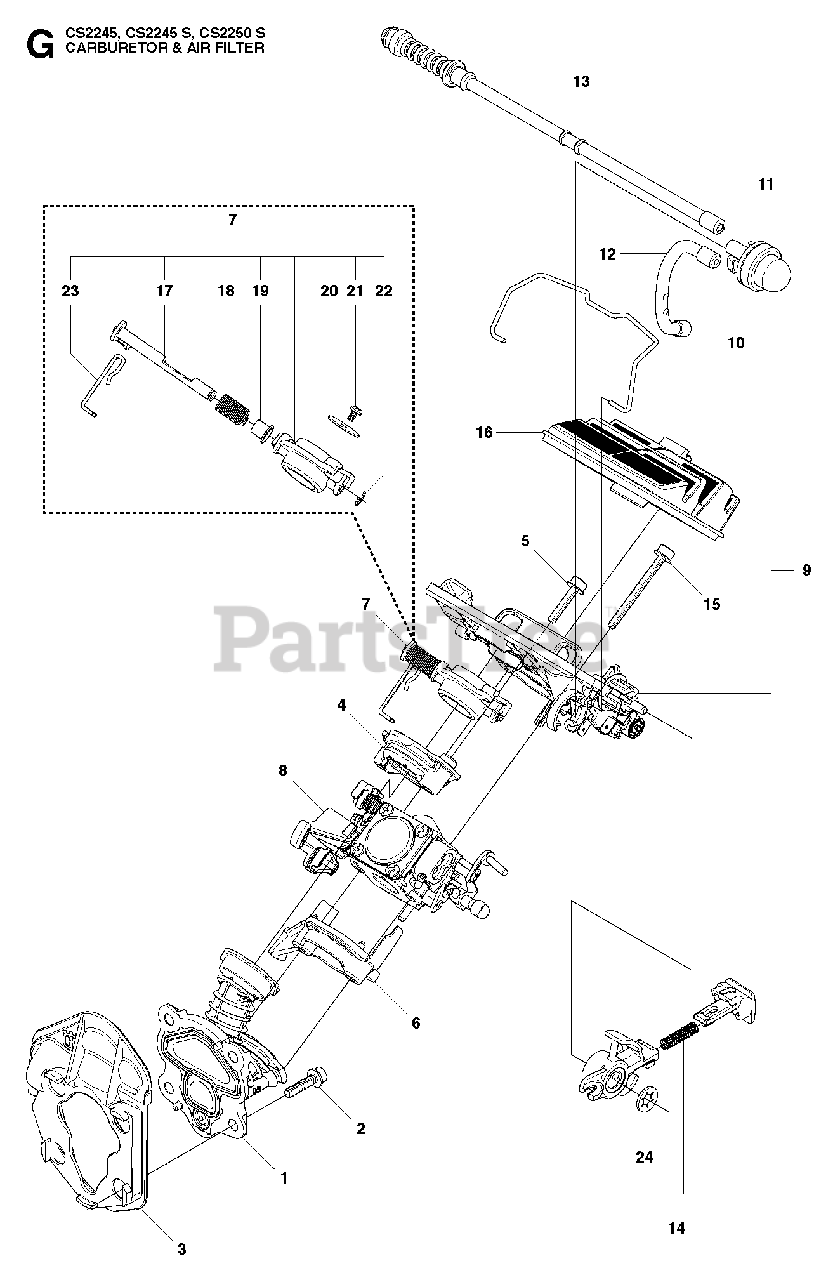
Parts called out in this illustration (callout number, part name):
1	INLET PIPE ASSY
3	INTERMEDIATE WALL
8	CARBURETOR
9	%FILTER HOLDER
10	SHACKLE
11	AIR PURGE BUBBLE
13	RP RETURN HOSE
16	AIR FILTER - NYLON (80)
16	AIR FILTER - NYLON (44)
16	AIR FILTER - FELT
17	SHAFT ASSY
18	SPRING
19	COLLAR
20	VALVE
21	SCREW
22	CLIP
23	ROD
24	LOCK WASHER
